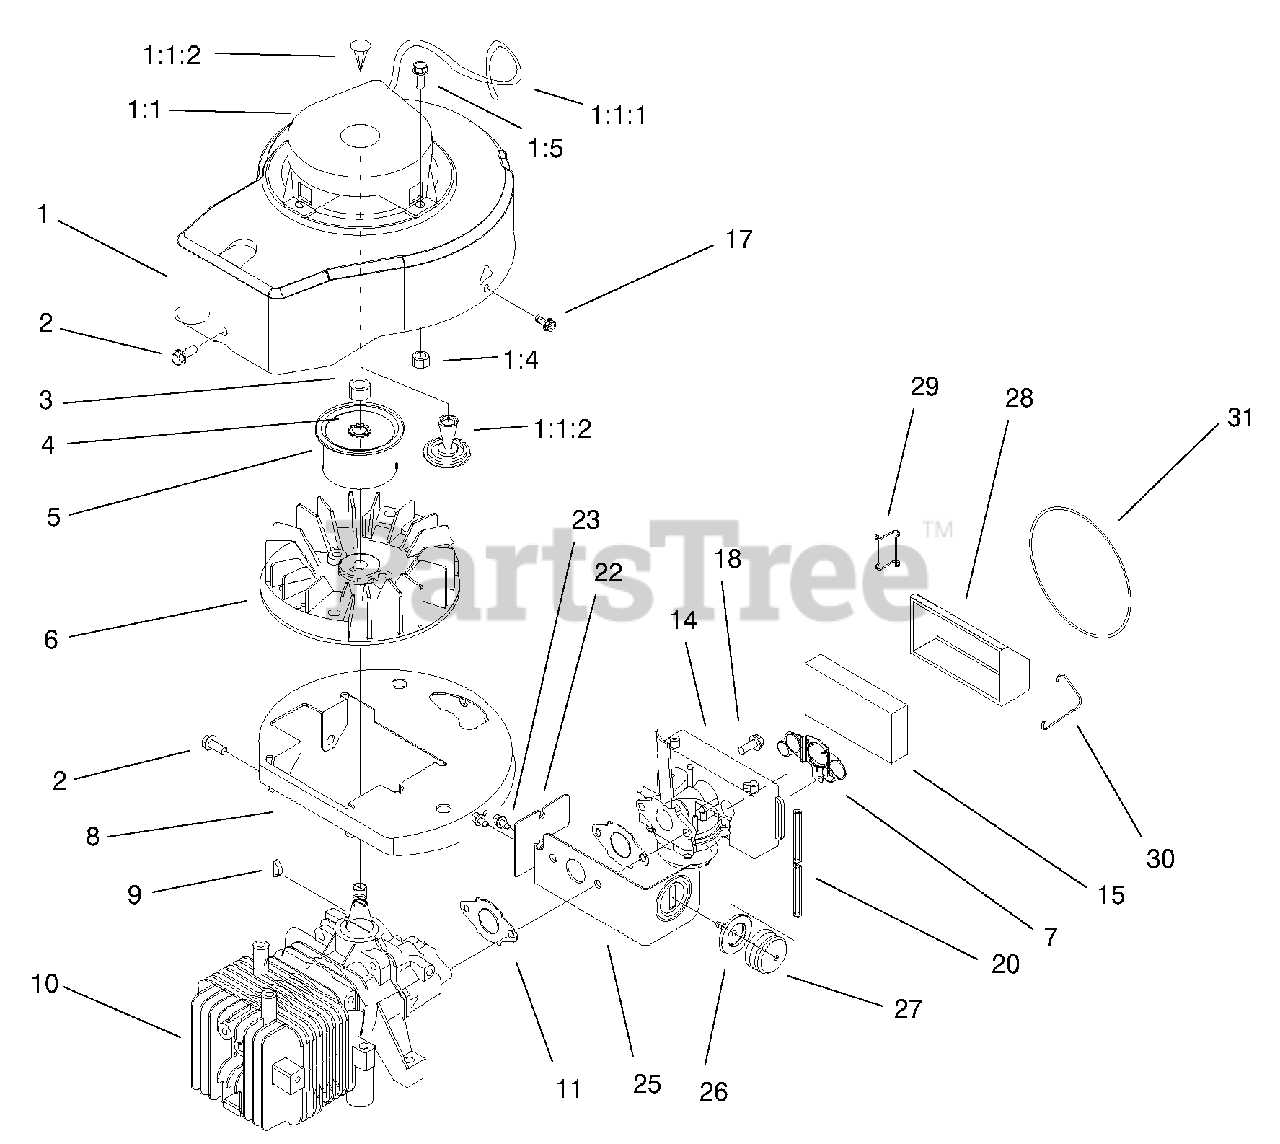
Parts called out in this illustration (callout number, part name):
1	Shroud/Start
1:1	Recoil
1:1:2	Retainer And Clip
1:4	Nut-Lock
1:5	Screw-HWH
2	Screw
4	Washer-Lock
5	Hub-Starter
6	Flywheel
7	Shield-Fuel
8	Base-Shroud
10	Short Block ASM
11	Gasket-Carburetor
14	Carburetor ASM
15	Element-Filter, Air
20	Hose-Primer
26	Body-Primer
27	Bulb-Primer
28	Cover-Filter, Air
29	Hook-Cover
30	Retainer-Cover
